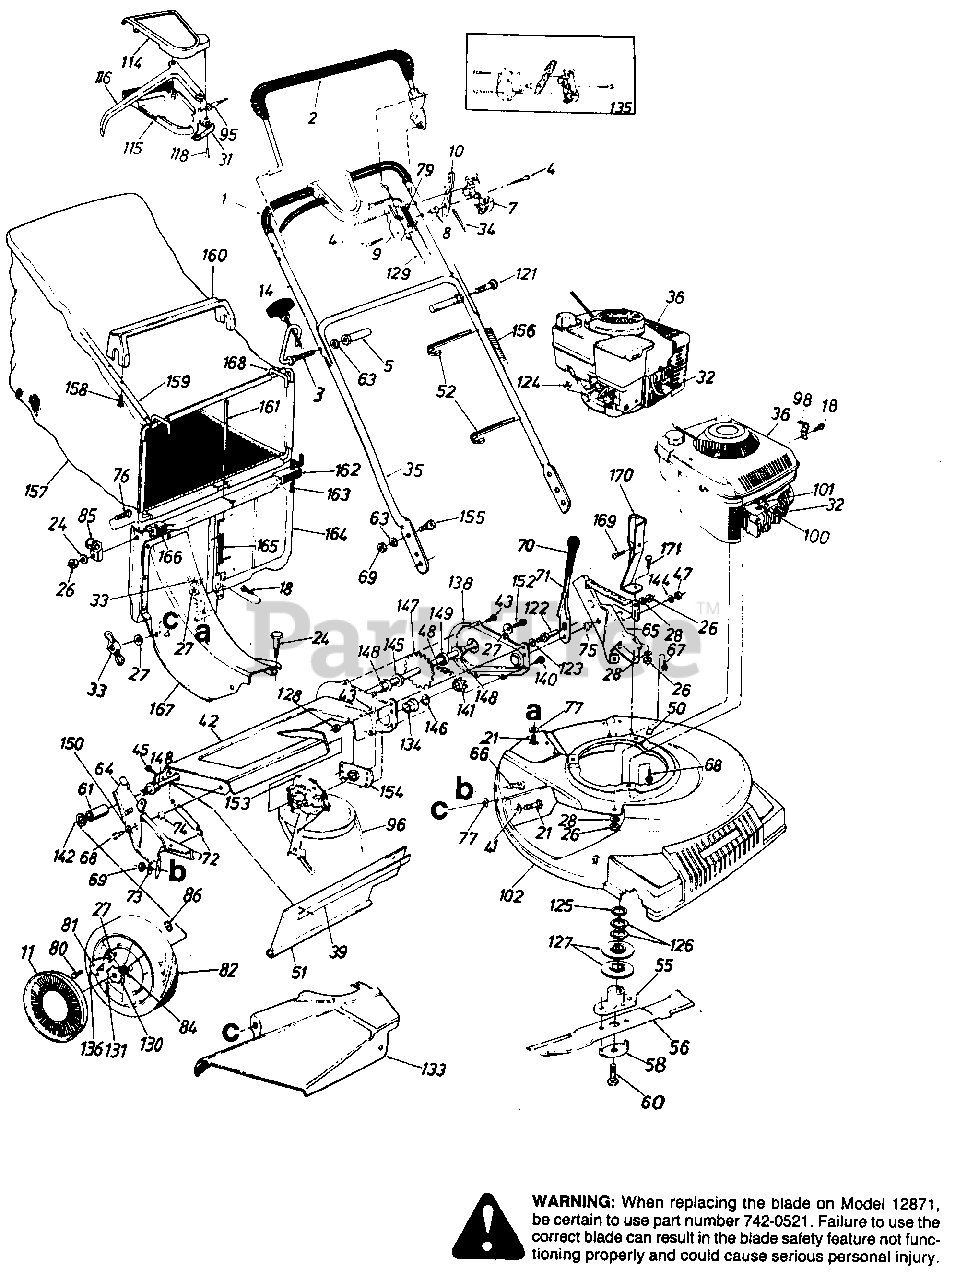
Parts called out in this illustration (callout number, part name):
2	Control Handle Ass'y. L.H.
3	Rope Guide Bolt
4	Truss Mach. Scr. #12 x 1.50" Lg.
5	Catcher Support Pin
7	Control Panel Half
8	Control Disc Pin
9	Clutch Panel Half
10	Throttle Control Lever
11	Hub Cap
14	Upper Handle Chrome
18	Hex B-Tap Scr. #10 x .38"
21	Carriage Bolt 1/4-20 x .62"
24	Shoulder Bolt Special
26	Hex Nut 1/4-20 Thd.
27	Bell-Wash. 1/4" I.D.
28	L-Wash. 1/4" I.D.
31	S.P. Control Cover
32	Spark Plug Insulator
33	Wing Nut
34	Throttle Control Wire 58"
35	Lower Handle Chrome
36	Engine
39	Retaining Strip
41	Fl-Wash. .344" I.D. x .62"
42	Chain Axle Ass'y.
43	Hex B-Tap Scr. 1/4" x .38"
45	Hex AB-Tap Scr. 1/4 x .62"
47	Hex Patch L-Nut 3/8-24 Thd.
48	#48 Chain .500" Pitch x 30 Links
51	Rear Flap 3.75" x 17.30" Lg.
52	Cable Tie
55	Blade Adapter Kit
56	21" Blade
58	Blade Bell-Wash. .45" I.D.
60	Hex Bolt 7/16-20 x 1.5"
61	Spacer.513" I.D.
63	L-Wash. 5/16" I.D.
64	R.H. Handle Wheel Brkt. Ass'y.
65	L.H. Handle Wheel Brkt. Ass'y.
66	Carriage Bolt 5/16-18 x .62"
67	Hex Wash. Hd. B-Tap Scr. 5/1 6-1 8
68	Hex Wash. Hd. TT-Tap Scr. 3/8- 1 6
69	Hex Nut 5/16-18 Thd.
71	Height Adj. Lever
72	Extension Spring 3.80" Lg.
73	Bell-Wash. 5/16" I.D.
74	Spacer.385" I.D.
75	Shld. Spacer.5" Dia.
76	Truss Mach. Scr. 1/4-20 x .5" Lg.
77	Bolt Retainer 1/4 x .50" O.D.
79	Control Label
80	Shld. Scr. .342" Dia. x .268
81	Pawl
82	Wheel Ass'y. Comp. Rear
84	Sleeve Bearing 1/2" I.D.
85	Rope Guide
86	Flat Nut 1/4-20 Thd.
95	S.P. Cable 50" Lg.
96	"V"-Belt
98	Casing Clamp
100	Hex B-Tap Scr. #10 x .62"
101	Casing Clamp
115	Self-Propelled Control Cover
116	Control Lever
118	Fl-"C"-Sunk Hd. Tap Scr. #10 x .75" Lg.
121	Curved Carr. Bolt 5/16-18 x 1.75" Lg.
122	Shld. Pin 1.43 Lg.
123	L-Wash. 3/8" I.D.
124	Hex Nut 3/8 x 16 Thd.*
125	Serrated Wash. 1.0" I.D.
126	Wave Wash. 1.005 I.D.
127	Serrated Pulley Half
128	Hex Nut 3/8-24 Thd.
129	Control Cable 46"
130	Ratchet Wheel 1.62" O.D.
131	Cotter Pin 1/8" Dia. x 1"
133	Side Chute Deflector Ass'y.
134	Flange Bearing
135	Kit Control Housing Comp.
136	Spring Nylon
138	Chain Cover
140	Hex S-Tap Scr. 1/4-20 x .50"
141	Sprocket Shaft Ass'y.
142	Fl-Wash. .510" I.D. x 1.0"
144	Fl-Wash. .385" I.D. x .87"
145	Fl-Wash. .51" I.D. x 1.0"
146	Fl-Wash. 3/8" I.D.
147	Rear Shaft Ass'y. 21.94" Lg.
148	Hex Flange Brg. .506" I.D.
149	Fl-Wash. .531 I.D. x .930
150	Fl-Wash. 3/8" I.D.
152	Hex Bolt 1/4-20 x .62" Lg. (Grade 5)
153	Transmission Comp.
154	Hex Bearing Cup
155	Truss Mach. Scr. 5/16-18 x .75" Lg.
156	Plastic Tubing
157	Grass Bag
158	Hex AB-Tap Scr. #12 x 1.25" Lg.
161	Chute Rod .188" Dia.
162	Door Clip
163	Hex AB-Tap Scr. 1/4 X .75"
164	Chute Door
165	Torsion Spring
166	Panel Clip
167	Top Discharge Chute Ass'y.
168	Front Catcher Frame
